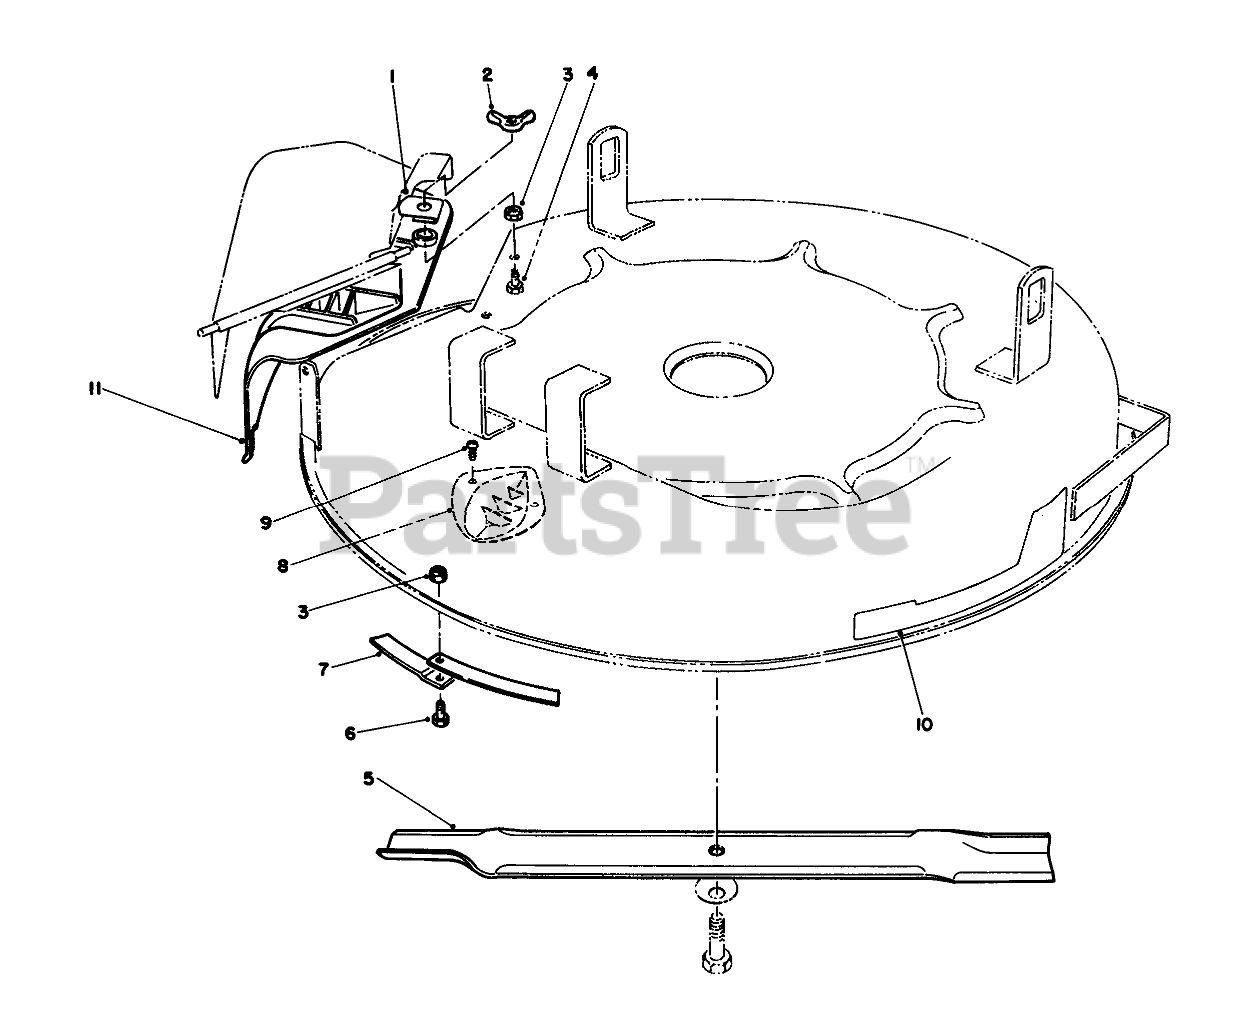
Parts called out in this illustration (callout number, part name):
2	NUT-WING SPECL
3	NUT-LOCK, NI
4	SCREW-HHF
5	Blade
6	SCREW-HH
7	Ring-Deck
8	KICKER
9	#8 X .625" PHILPS PAN H
10	DECAL - RECYCLER
11	COVER- 25" (W/KICKER)
